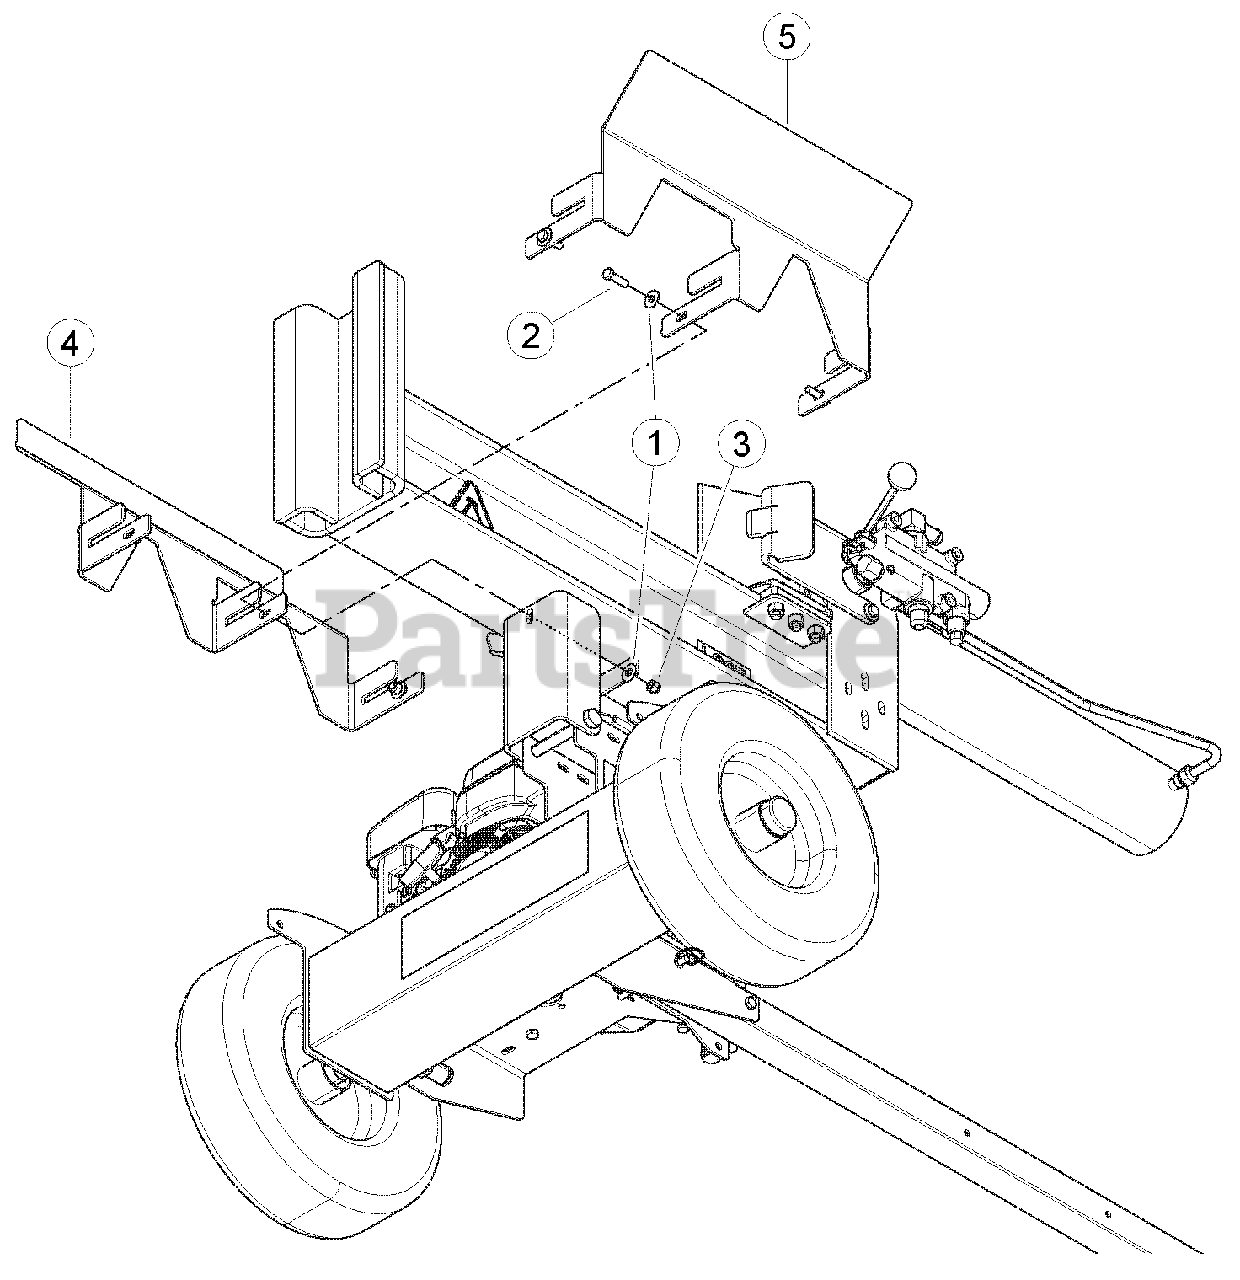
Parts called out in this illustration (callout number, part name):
1	WASHER, 3/8 FLAT ZP
2	BOLT, 3/8 X 1-1/4 HEX HD GR5 ZP
3	NUT, 3/8 NE NYLOCK ZP
4	CRADLE, LOG SPLITTER
5	CRADLE, LOG SPLITTER
